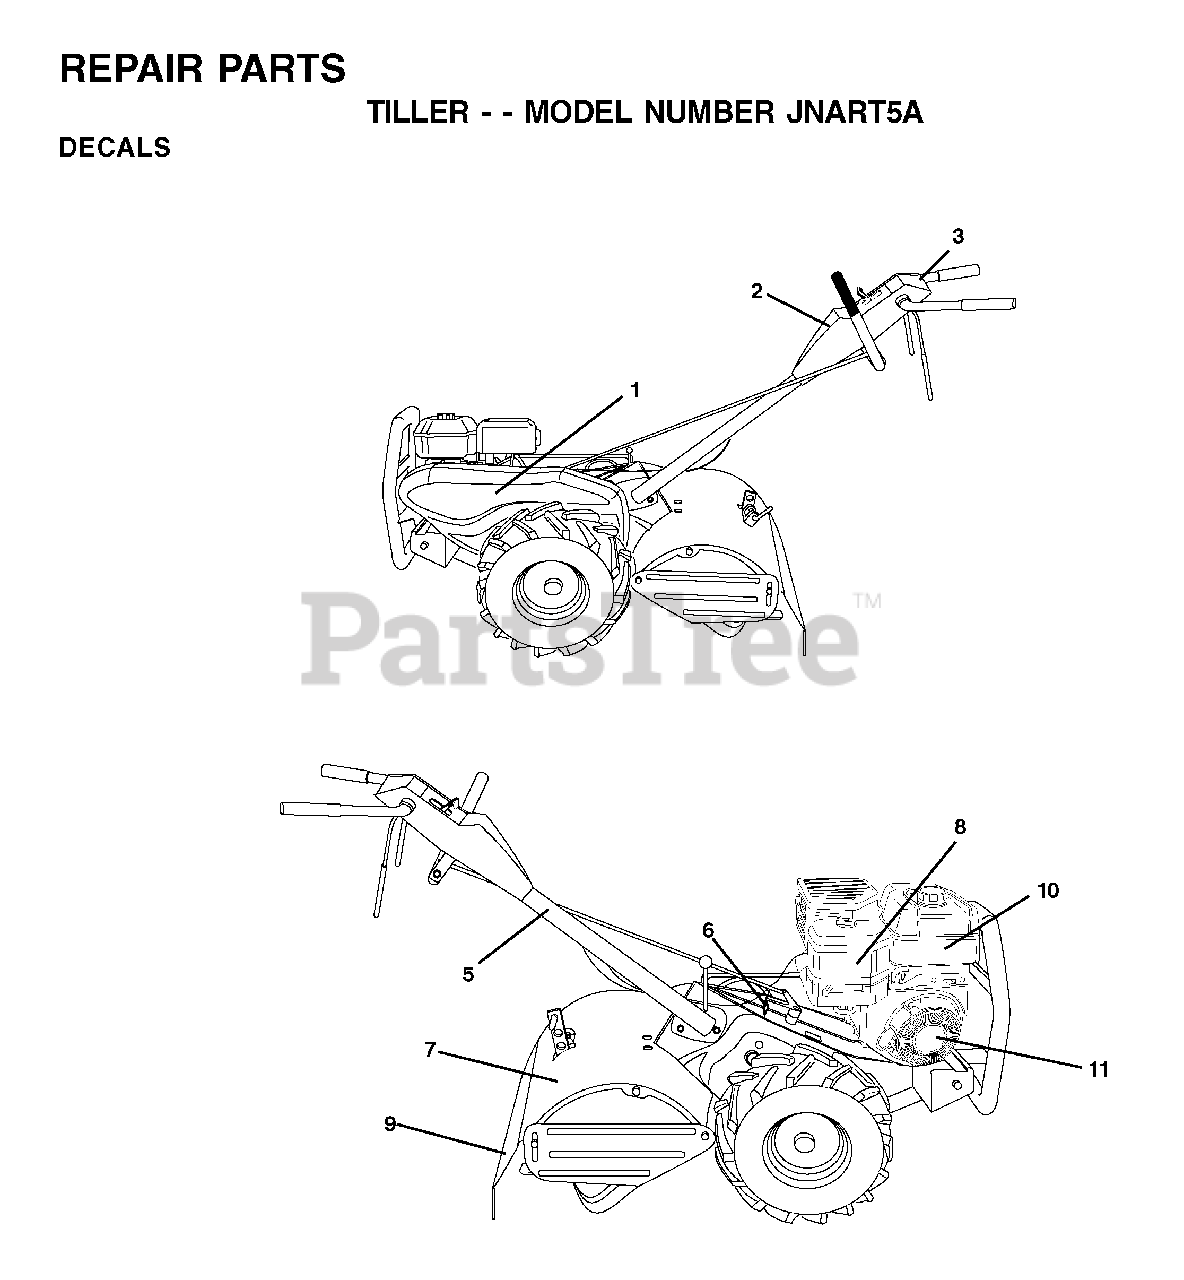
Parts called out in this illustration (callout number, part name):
3	DECAL INST CONTROL PANEL
6	DECAL.SHIFT.INDICATOR.TILLER
7	DECAL -CAUTION
9	DECAL TI
11	DECAL.REWIND
